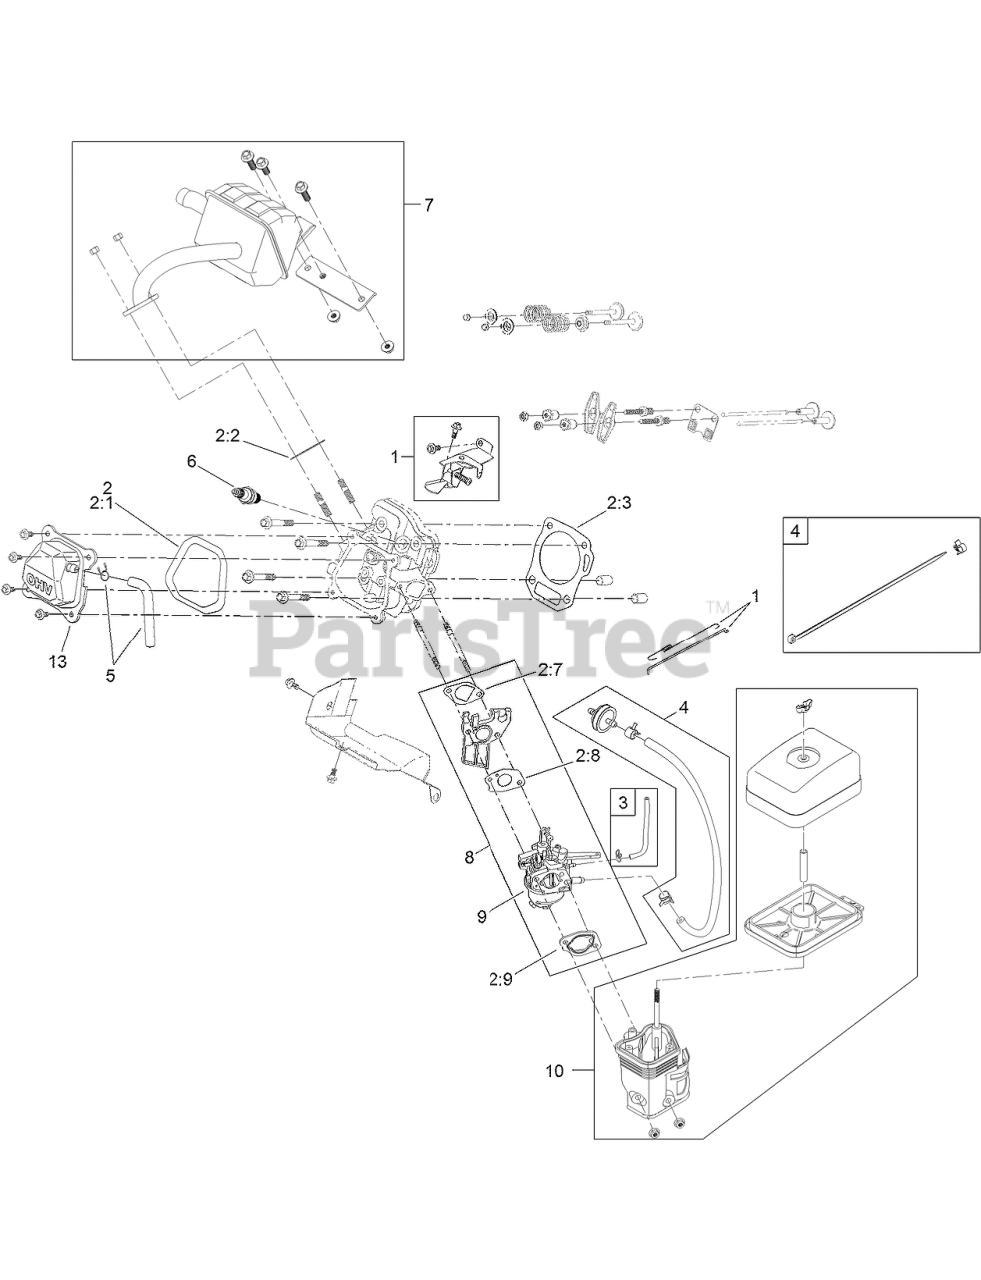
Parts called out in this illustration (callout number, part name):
1	GOVERNOR KIT
2	GASKET AND SEAL KIT
2:1	GASKET-COVER, VALVE
2:2	Gasket-Exhaust
2:3	GASKET-HEAD, CYLINDER
2:7	GASKET-CARBURETOR
2:8	GASKET-CARBURETOR
2:9	GASKET-CARBURETOR
3	PRIMER LINE KIT
4	FUEL LINE KIT
5	BREATHER TUBE KIT
6	PLUG-SPARK
7	MUFFLER KIT
8	CARBURETOR KIT
9	CARB REPAIR KIT WITH GASKETS
10	HEATER BOX KIT
13	VALVE COVER ASM
